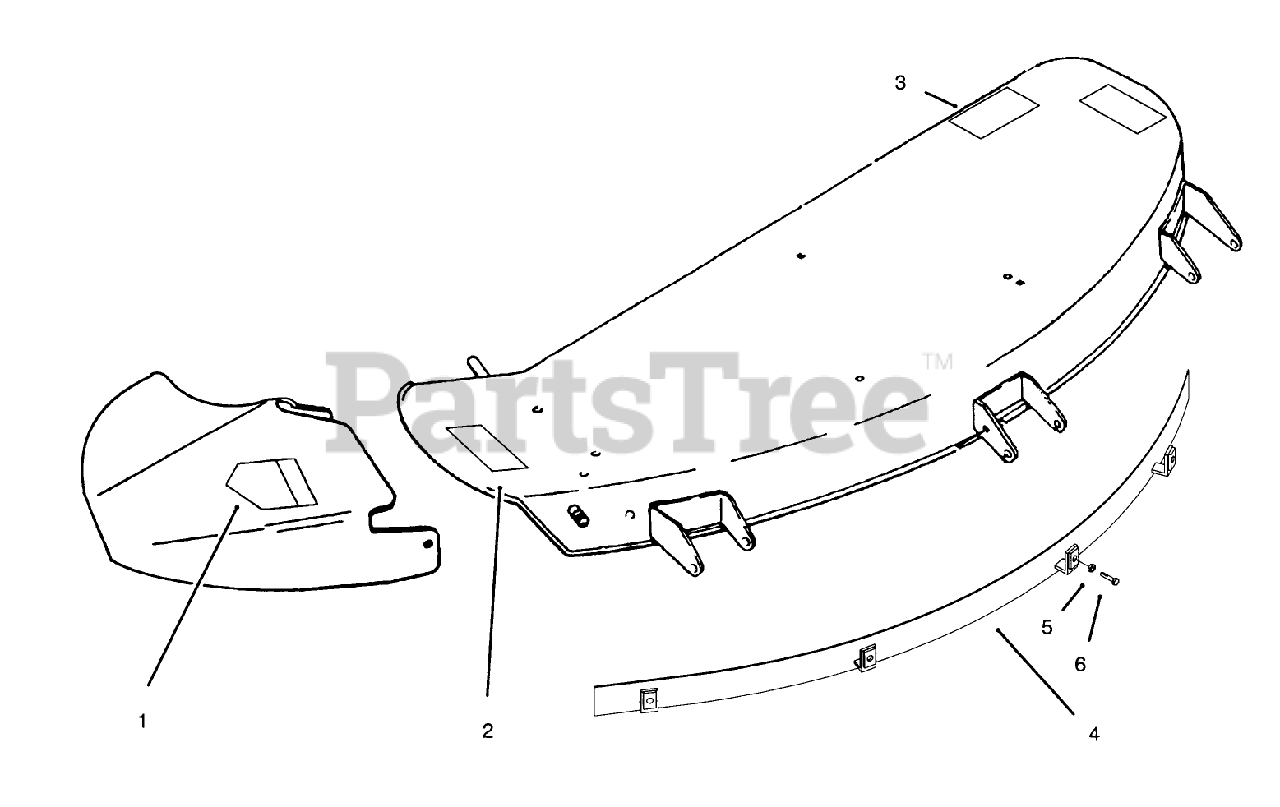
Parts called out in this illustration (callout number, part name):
1	DECAL-DANGER
2	DECAL-DANGER
3	DECAL - BELT & HEIGHT
4	Shield
5	NUT-JAM
6	Screw-Hex Hd.
